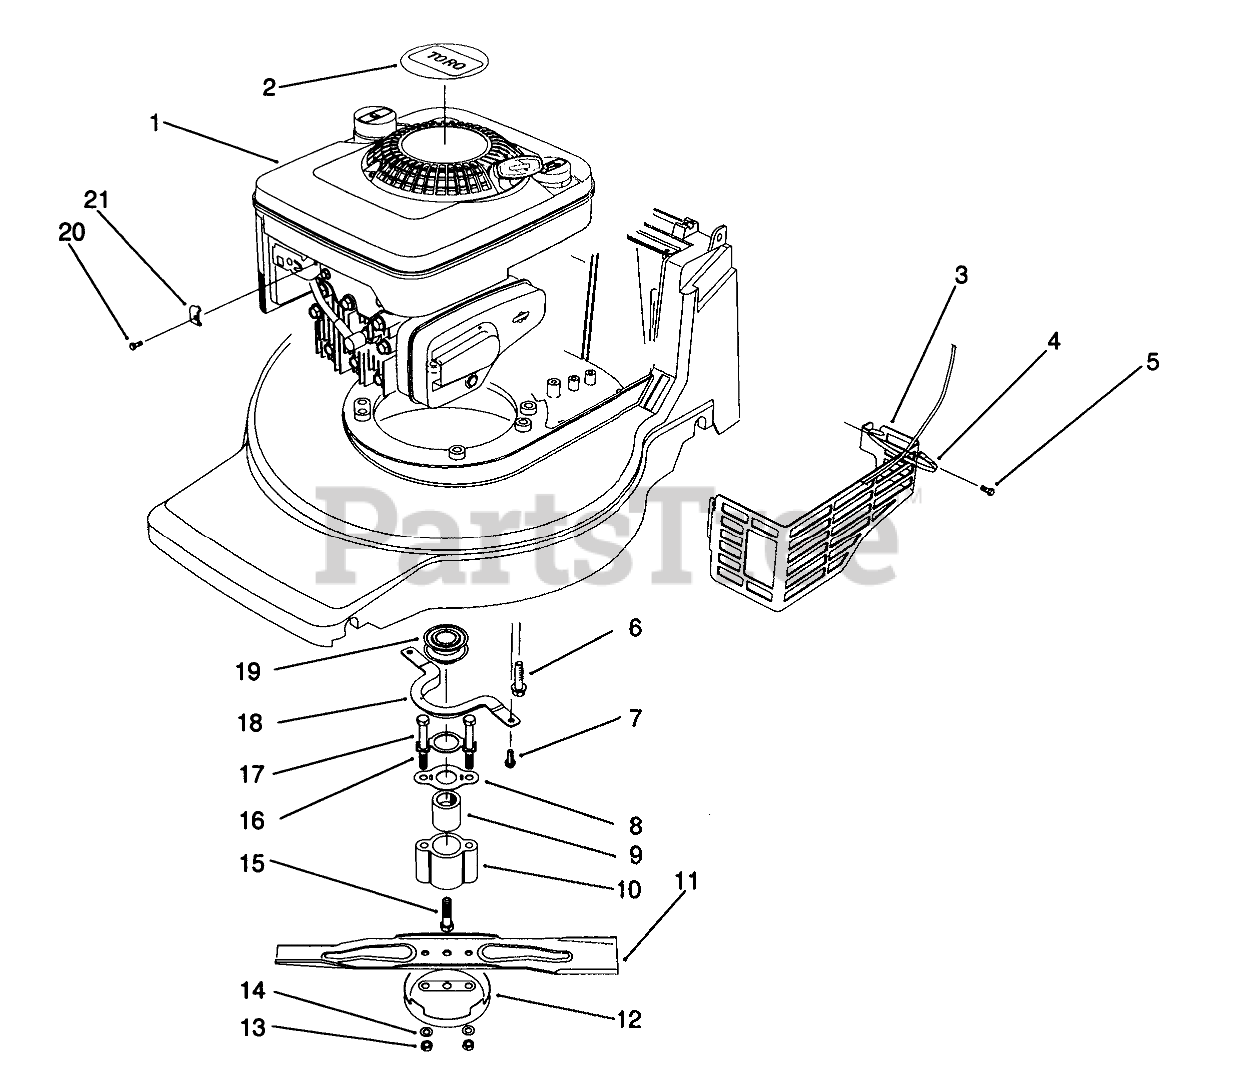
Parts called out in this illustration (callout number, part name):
1	Engine-B&S Quantum
2	DECAL - RECOIL
3	SHIELD-MUFFLER
4	TIE-CABLE
5	SCREW-HWH
6	3/8-16 X 2 CAPSCREW
7	SCREW-HWH
8	SPRING FRICTION
10	RETAINER
11	Blade-48cm
12	Anti Scalp Cup
13	Nut
14	WASHER
15	SCREW - CRANKSHAFT
16	BLADE RETAINER BRKT
17	SCREW - BLADE
18	Guide-Belt
19	PULLEY-DRIVE, ZONE START
20	Screw
21	CLAMP-CASING
